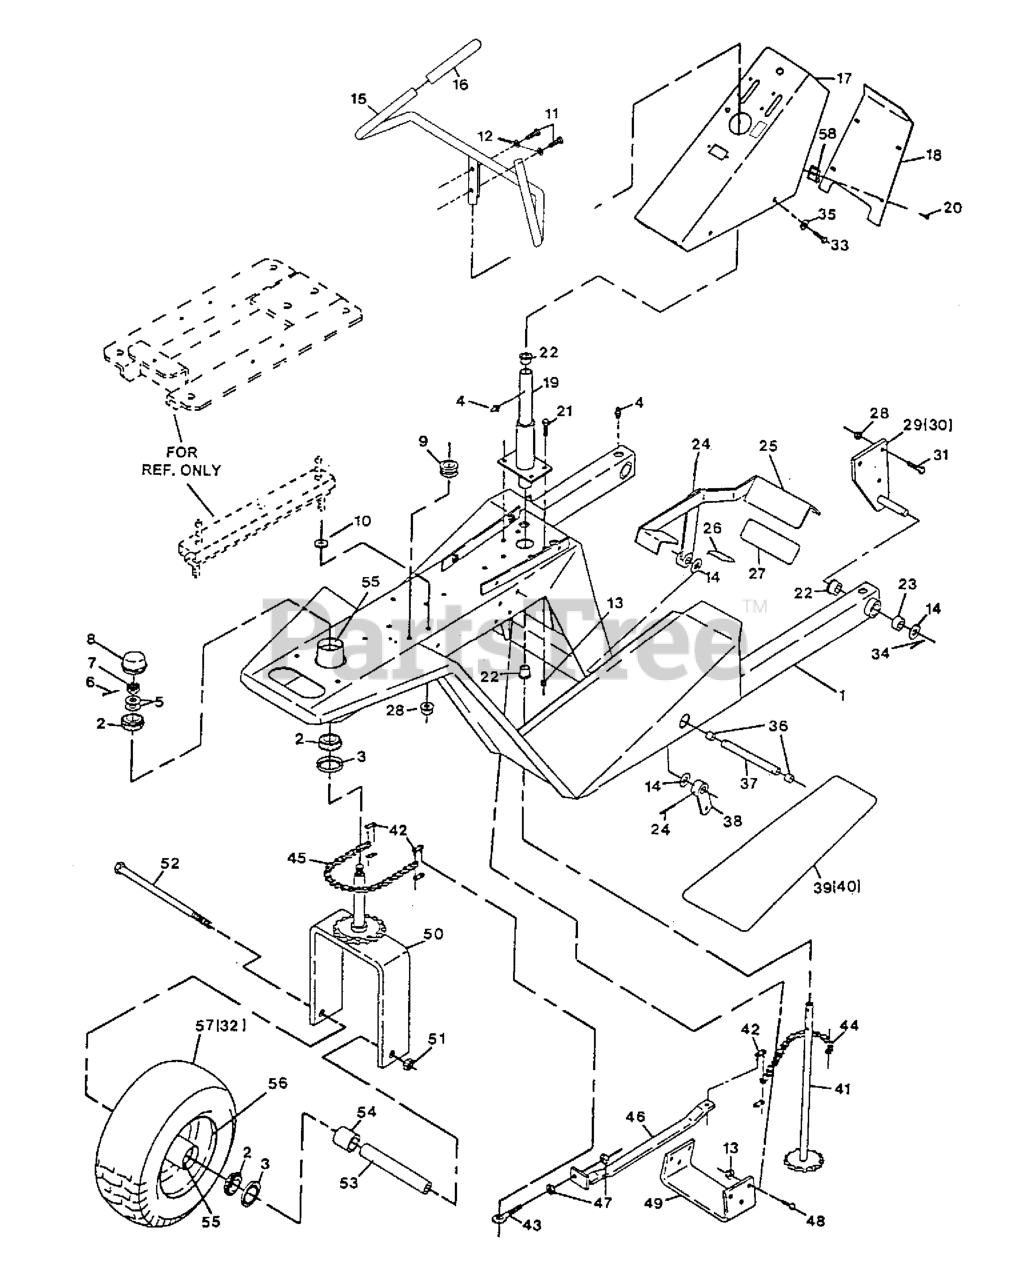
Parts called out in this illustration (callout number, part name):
2	Cone-Bearing Tapered Roller
3	SEAL-GREASE
4	FITTING-GREASE
5	WASHER-FLAT
6	PIN-COTTER
7	NUT-HEX, SLOTTED
8	CAP-GREASE
9	GROMMET
10	WASHER-FLAT
11	SCREW-HH
12	WASHER-BELLEVILLE
13	NUT-HHF, WHIZ
15	WLD,HANDLE BAR
18	PLATE-CONSOLE, FRONT
19	WLD,STEERING POST
20	SCREW-HWH
21	SCREW-HH
23	SLEEVE,BEARING
24	PIN,ROLL
27	PAD,ANTISKID
29	WLD,BRACKET PIVOT RH
31	SCREW-HH
32	TIRE ONLY 8NHS
33	SCREW-HH
35	WASHER-FLAT
37	Shaft, Foot Pedal
38	WLD,FOOT PEDAL LEVER
39	PAD,ANTISKID RH
41	WLD,STEERING SHAFT
43	EYEBOLT, RH
47	NUT-JAM
48	SCREW-HH
49	STOP,ACTUATOR
52	SCRW,CAP HH
53	BUSHING, WHEEL - PLT
54	SPACER,WHEEL SHORT
55	CUP-BEARING
56	WHEEL 8.00 W/HUB
57	ASM,WHEEL & TIRE
58	CLIP,SGLTHRD TYPU
